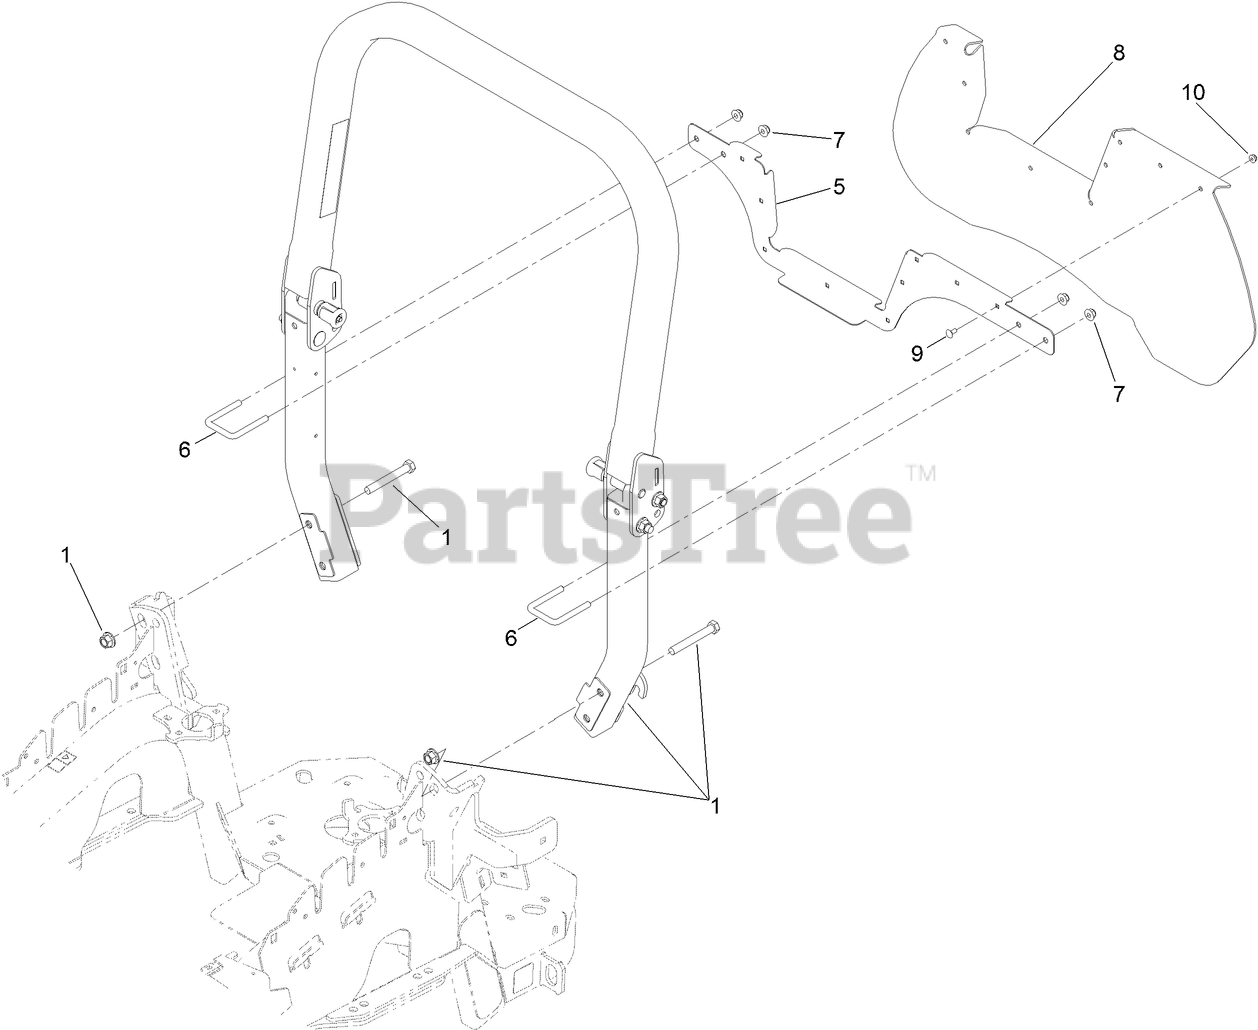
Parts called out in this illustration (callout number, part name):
1	ROPS ASM
5	BRACKET-AIR DAM
6	U-BOLT
7	NUT-HF, NI
8	HOOD-AIR DAM
9	SCREW-CARR
10	NUT-HF
